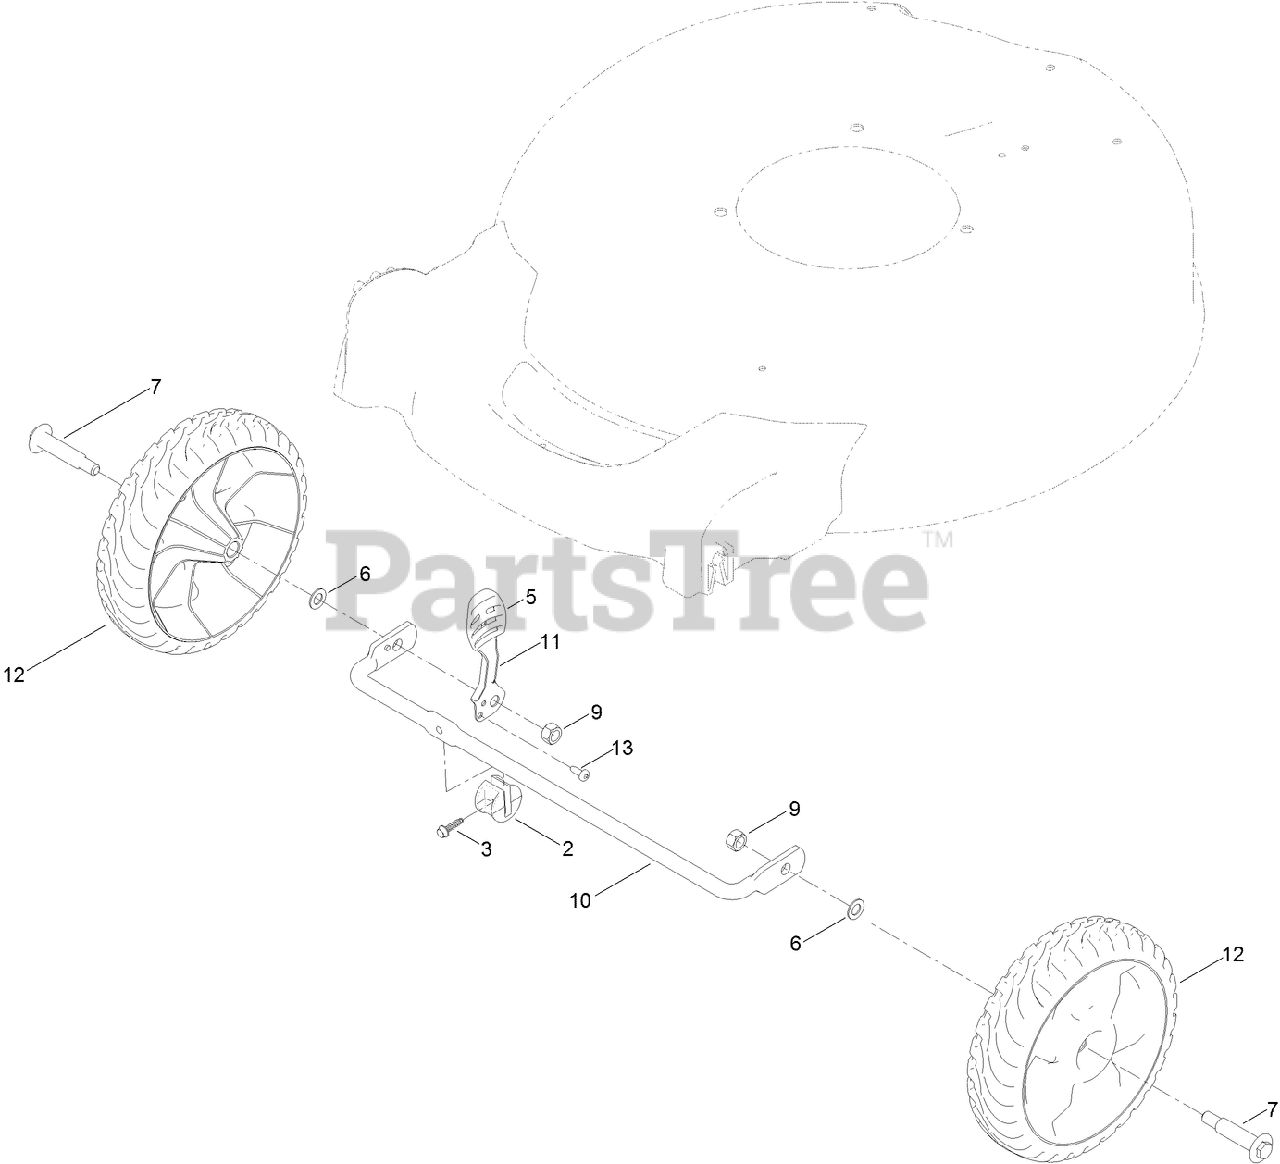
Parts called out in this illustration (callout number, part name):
2	STOP-AXLE
3	SCREW-HWH
5	Knob-Lever, HOC
6	WASHER
7	BOLT-SHOULDER
9	NUT-HEX
10	AXLE-FRONT
11	ARM-SPRING
12	8 INCH WHEEL ASM
13	SCREW-FORMING, THREAD
